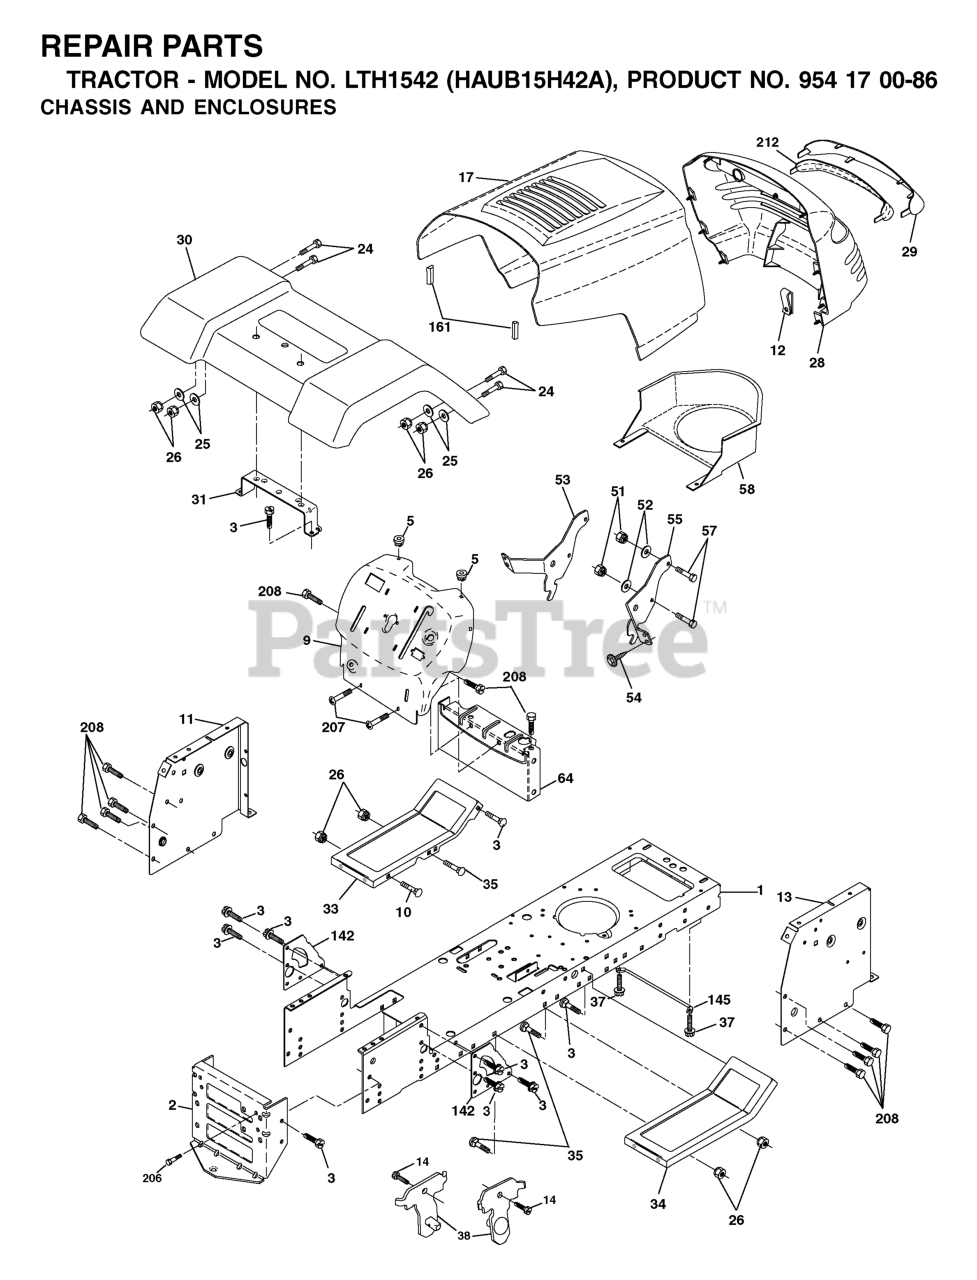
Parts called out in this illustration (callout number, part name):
1	RP.SWITCH, BLADE
2	HOUR METER
3	IGNITION SWITCH
4	THROTTLE CABLE DETENT
5	FENDER, CONSOLE
6	PLATE.CONTROL.CONSOLE.BLACK
7	SCR #10-12X3/4 HEX WAS HD ZD
8	HCS #10-24 X 1/2
9	LENS, COLORED LEFT
10	RT HEADLIGHT RIM GREY
